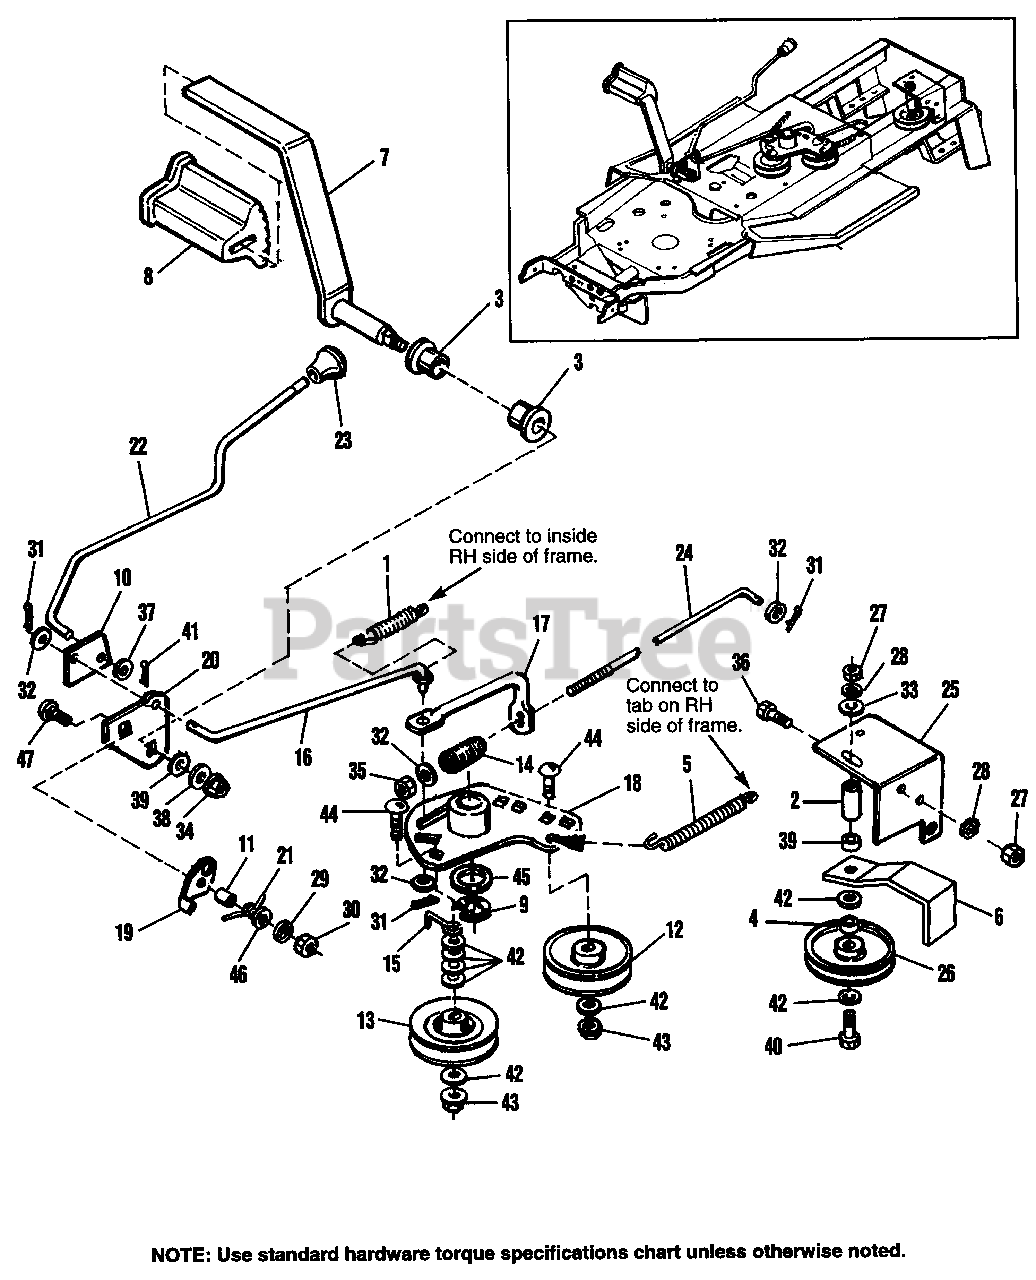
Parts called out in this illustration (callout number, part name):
1	SPRING, Extension
2	SPACER, 25/64 x 1 x 1-7/32
3	BUSHING, Plastic
4	SPACER, 3/8 x 43/64 x 29/64
5	SPRING, Drive
6	GUARD, Spring "L"
7	BRAKE PEDAL ASSY.
8	PAD, Brake Pedal Assy.
9	KLIP RING, 5/8
10	CAM, Parking Brake
12	PULLEY, Idler, Backside
13	PULLEY, V, Idler
16	ROD, Clutch
17	ARM ASSY., Brake
18	IDLER ARM ASSY.
19	SWITCH, Actuator
20	ARM, Brake Pedal Assy.
21	SPRING, Tension
22	ROD, Parking Brake
25	BRACKET, Idler
27	NUT, Hex, 3/8-16
28	LOCKWASHER, 3/8
29	LOCKWASHER, 5/16
30	NUT, Hex, Full, 5/16-18
31	COTTER PIN
32	WASHER, Plain, 5/16
33	WASHER, Plain, 3/4
34	NUT, Hex Nyloc, 5/16-18
35	NUT, Hex, Esna, 3/8-16
36	CAPSCREW, Hex Hd., 3/8-16 x 1
37	WASHER, Plain, 1/4
38	WASHER, 13/32 x 1-1/4 x 1/16
39	WASHER, Plain, 3/8
40	CAPSCREW, Hex Hd., 3/8-16 x 3-1/4
41	COTTER PIN, 1/16 x 3/4
42	WASHER, Plain, 3/8
43	NUT, Hex, Flange, Whiz, 3/8-16
44	CARRIAGE BOLT, 3/8-16 x 1-3/4
45	WASHER, 5/8 I.D. x 1-1/4 O.D. x 5/64 Thk.
46	WASHER, 21/64 I.D. x 1-1/4 O.D. x 5/64 Thk.
47	CARRIAGE BOLT, 5/16-18 x 1-1/4
